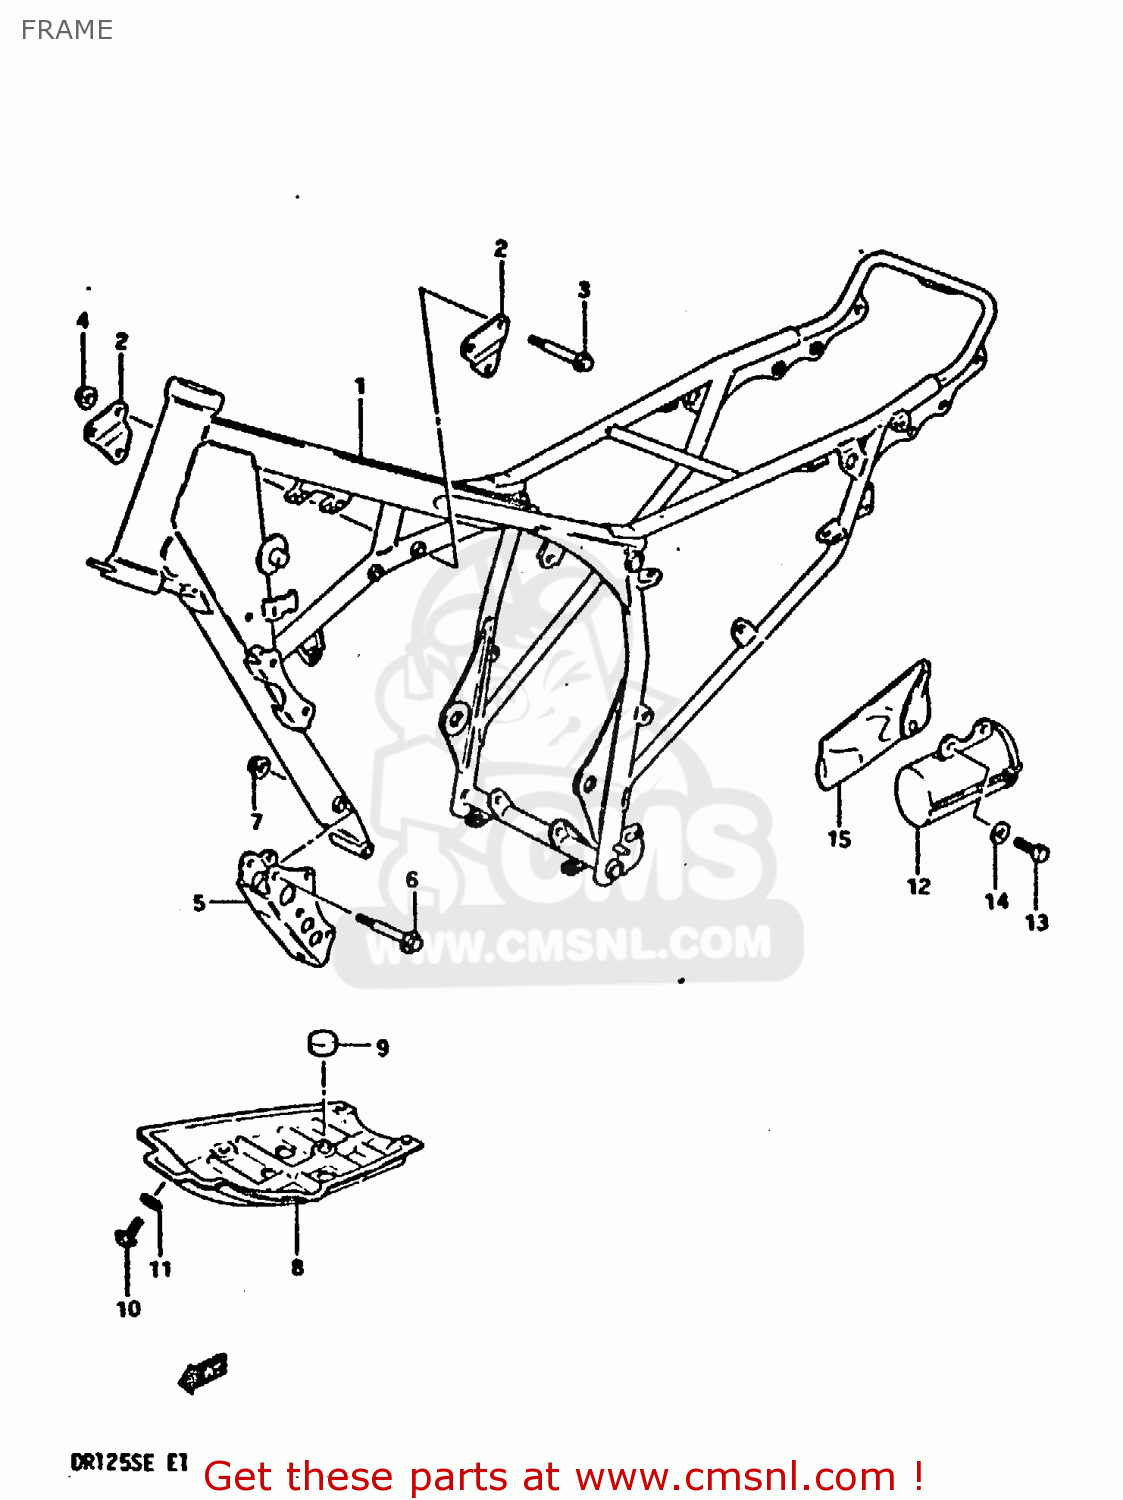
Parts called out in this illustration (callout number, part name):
1	FRAME (BLUE)
2	PLATE,ENGINE MOUNTING
3	BOLT (8X50)
4	NUT
5	PLATE,ENGINE MOUNTING
6	BOLT (8X65)
7	NUT
8	PROTECTOR,ENGINE
9	CUSHION
10	BOLT
11	WASHER
12	HOLDER,TOOL
13	BOLT, UPPER
14	WASHER (6.5X18X1.6)
15	TOOL SET
